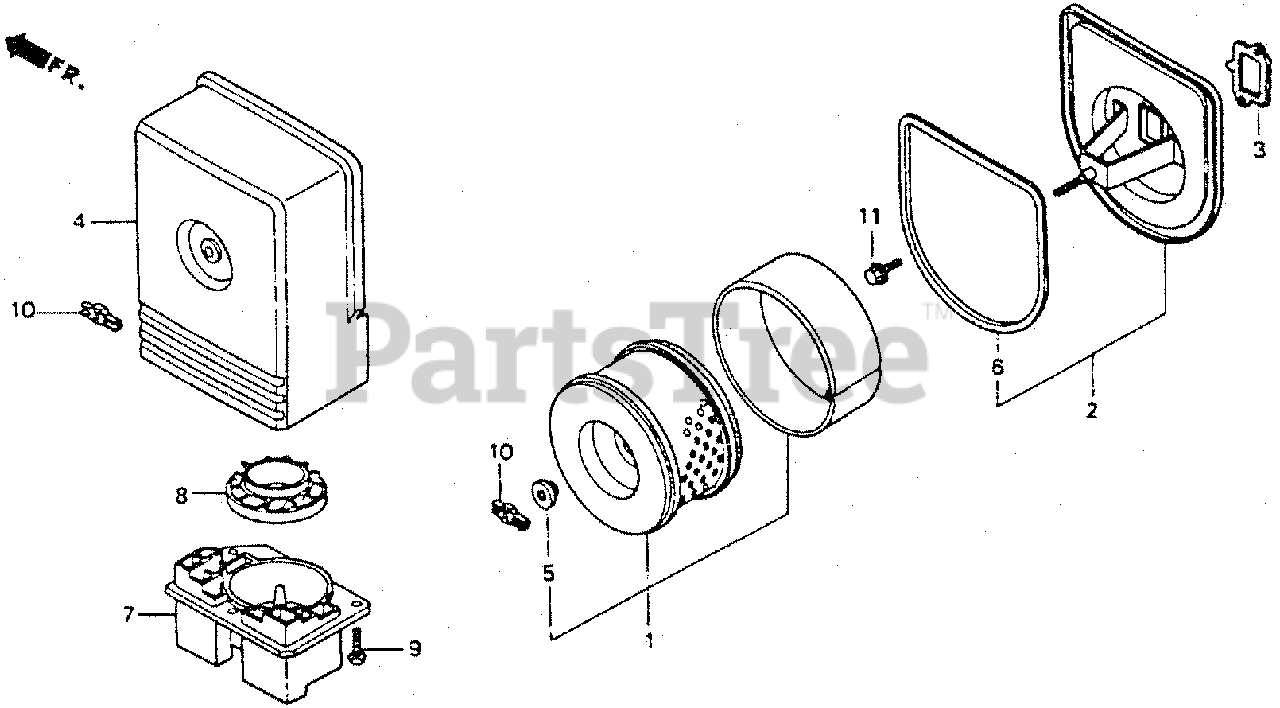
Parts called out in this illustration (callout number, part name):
1	ELEMENT, AIR CLEANER
2	HOUSING, AIR CLEANER
3	GASKET, AIR CLEANER
4	COVER, AIR CLEANER
5	GROMMET, AIR CLEANER
6	GASKET, AIR CLEANER HOUSING
7	CASE, PRE CLEANER
8	GUIDE, PRE AIR CLEANER
9	SCREW, PAN (5X16.5)
10	WINGNUT, AIR CLEANER COVER
11	BOLT, FLANGE (8X22)
